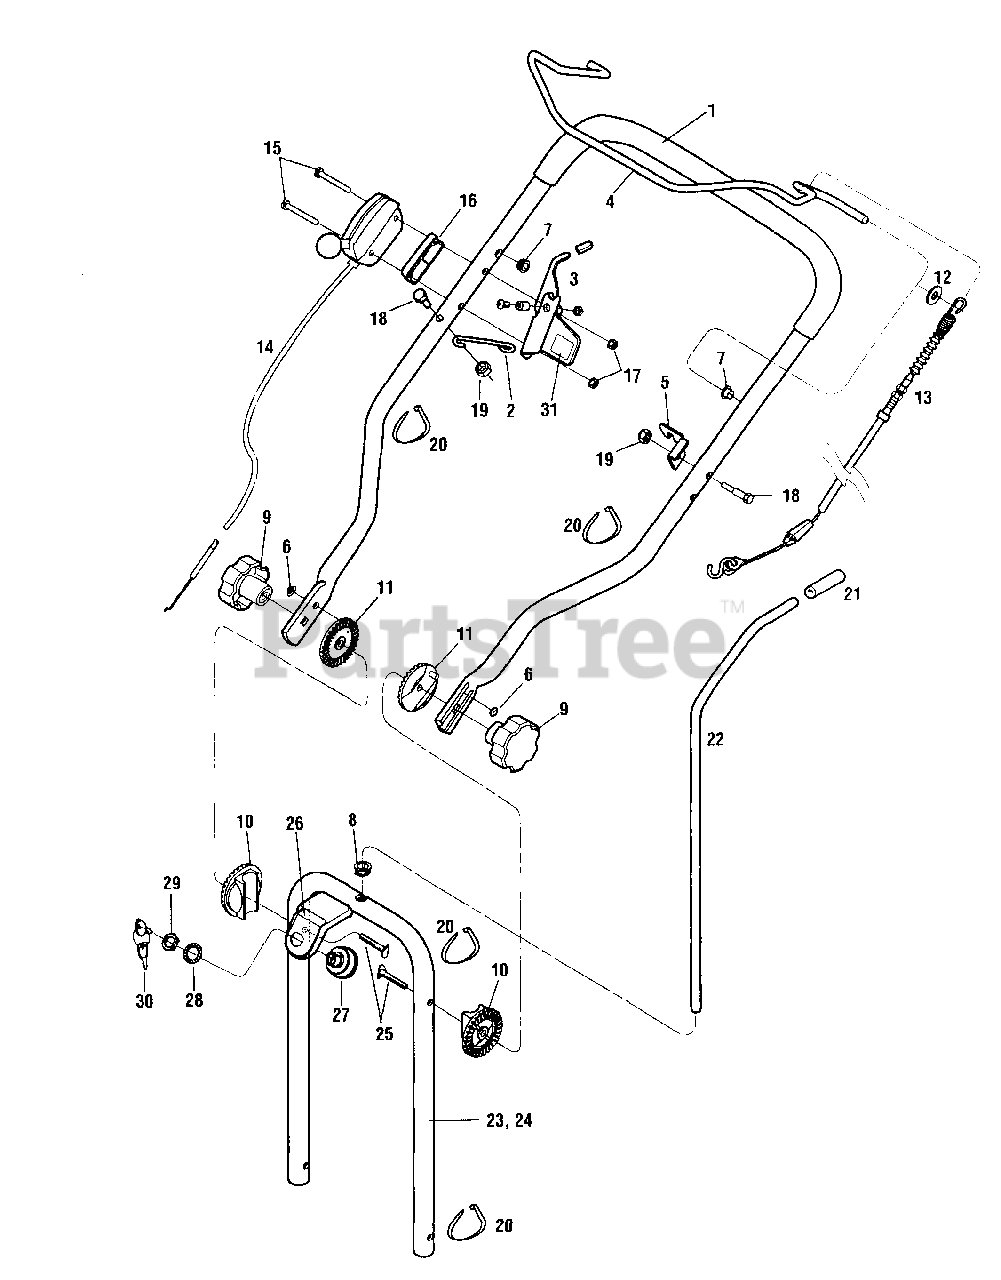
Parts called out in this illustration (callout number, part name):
1	Upper Handlebar w/sleeve
2	Rope Guide
3	Bail Stop/Latch Assembly
4	Bail
5	Cable Bracket
6	Push-on Retainer
7	Nyliner Bushing
8	Nyliner Bushing
9	Adjusting Knob
10	Inside Hndlbr. Adj. Quadrant
11	Outside Hndlbr. Adj. Quadrant
12	Flat Washer, 5/16
13	Control Cable
14	Throttle Cable
15	Screw, 10-24 x 2
16	Spacer
17	Lock Nut, 10-24
18	Hex Hd. Screw, 1/4-20 x 1-1/8
19	Top Lock Nut, 1/4-20
20	Cable Tie
21	Steering Rod Grip
22	Upper Steering Rod
23	Lower Handlebar.
24	Lower Handlebar.
25	Curved Hd. Bolt, 5/16-18 x 2
26	Decal-Keyswitch
27	Ignition Switch
28	Lockwasher, 5/8
29	Hex Nut, 5/8-32
30	Ignition Key
31	Bail Latch Decal
